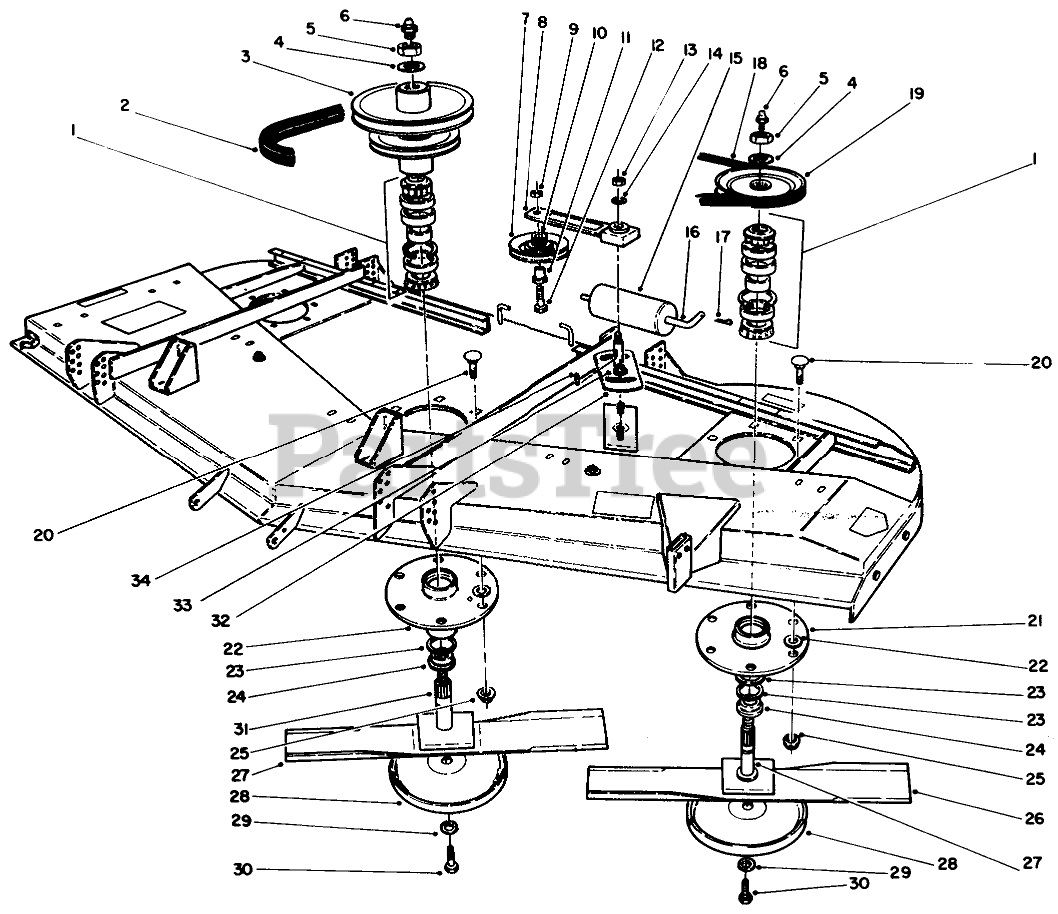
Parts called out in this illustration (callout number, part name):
1	BEARING ASM
2	V-BELT, DECK DRIVE
3	Pulley & Hub Assembly
4	WASHER
5	NUT-HEX
6	FITTING-GREASE
7	PULLEY-IDLER
8	IDLER ARM ASM
9	NUT-LOCK
10	WASHER-FLAT
11	BUSHING-PULLEY
12	SCREW-HH
13	NUT-LOCK NI
14	WASHER-FLAT
15	ROLLER-DECK
16	SHAFT-ROLLER, REAR
17	PIN-COTTER
18	V-BELT
19	PULLEY AND HUB ASM
20	SCREW-CARR
21	HOUSING-SPINDLE
22	WASHER-FLAT
23	SEAL-OIL
24	SPACER
25	NUT-HF
26	Blade
27	SHAFT
28	CUP-SCALP, ANTI
29	WASHER
30	SCREW-BLADE
31	Shaft-Spindle
32	PLATE-IDLER, LH
33	NUT-HHF, WHIZ
34	KEY-SQUARE
